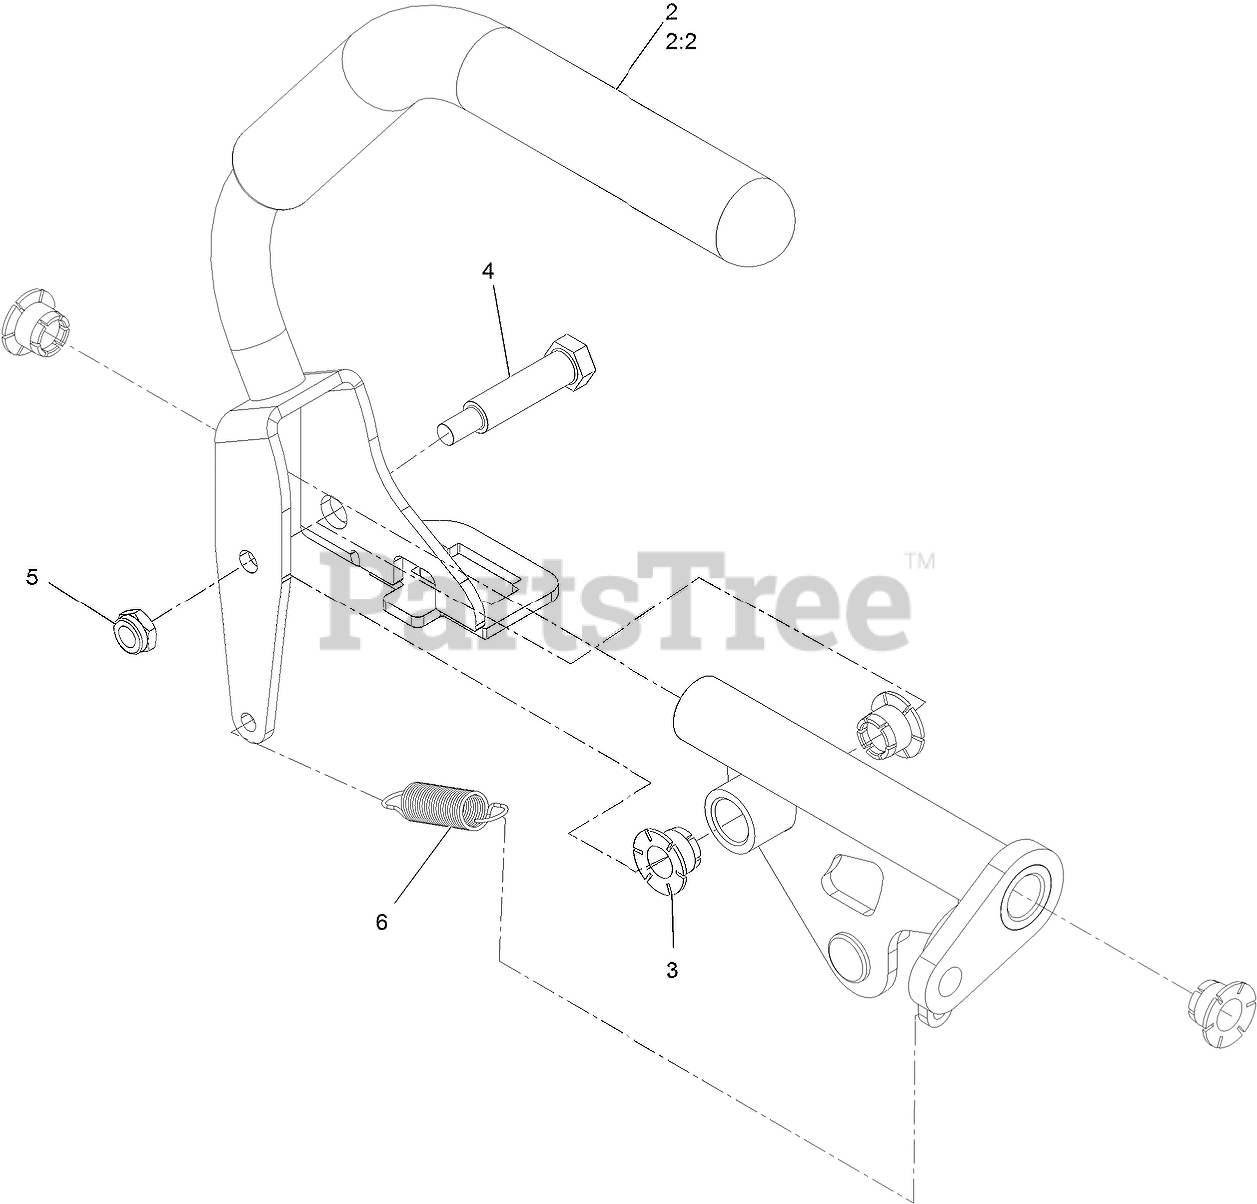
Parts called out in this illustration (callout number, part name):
2	ASM, LT CONTROL LEVER W/ GRIP
2:2	GRIP, DRIVE LEVER
3	BEARING, IGUS
4	BOLT-SHOULDER
5	NUT-LOCK, NI
6	SPRING-EXTENSION
